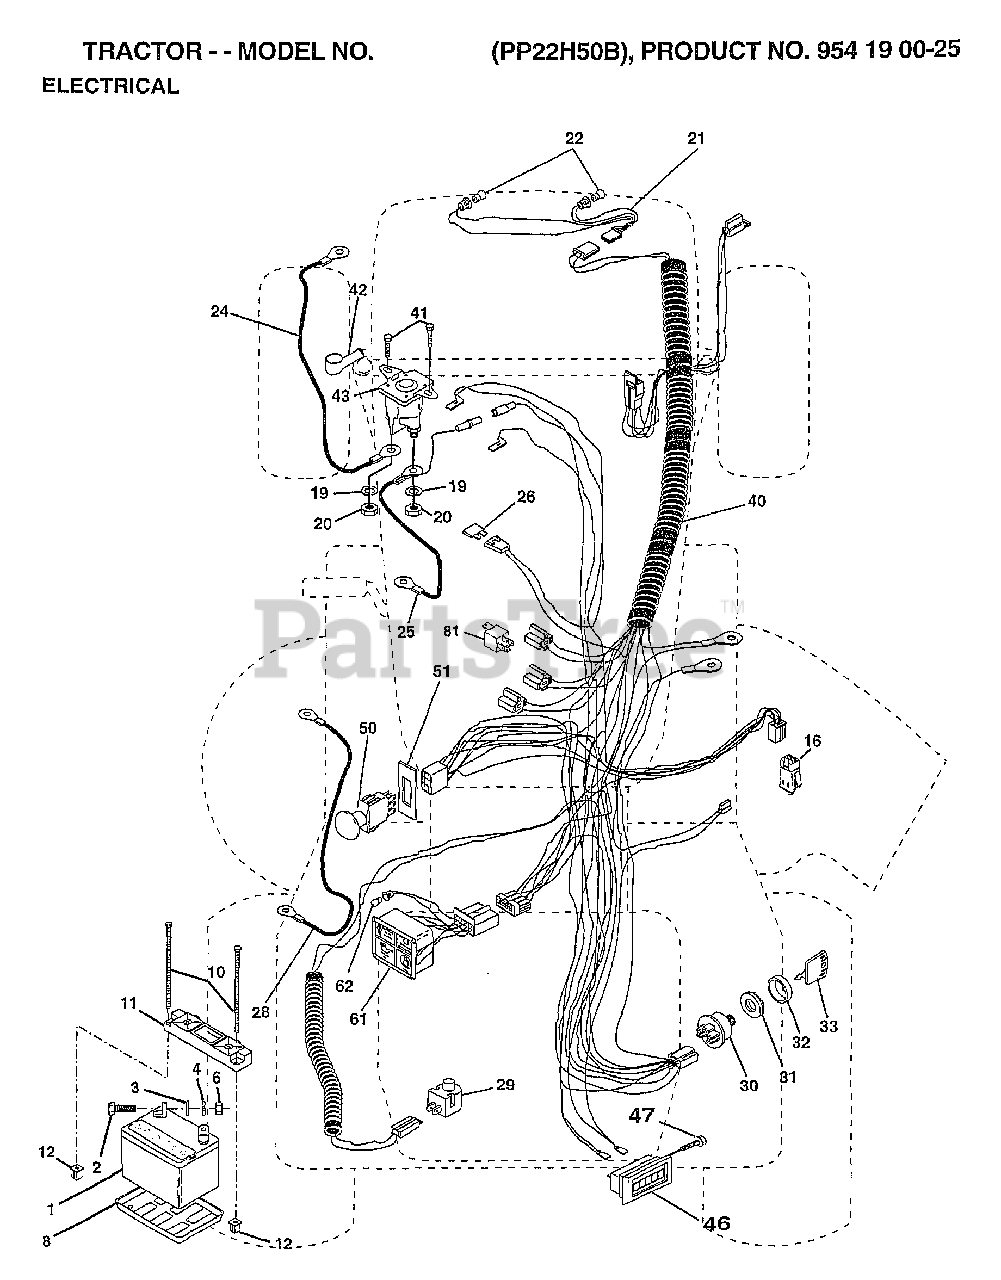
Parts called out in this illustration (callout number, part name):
2	BOLT LT
3	LOCKWASHER
4	WASHER
8	"TRAY T, BATTERY"
11	HOLDDOWN BATTERY
16	SWITCH INTERLOCK
20	NUT
21	"HARNESS,LIGHT SOC"
22	HEADLAMP BULB
24	CABLE.BATY.22.RED
25	CABLE.BATRY.4GA.
26	FUSE HYT
28	"CABLE BATTERY,GRD"
29	SWITCH.PLUNGER
30	SWITCH IGN 4POS
31	NUT IGNITION
32	COVER KEY SWITCH
33	KEY
40	HARNESS.IGNITION
41	SCREW
46	HOUR METER T
47	SCREW
50	PTO SWITCH.BLK
51	RING RETAIN PTO
61	LIGHT.PKG.ASM.
62	BULB LIGHT T
81	RELAY ASSY T
